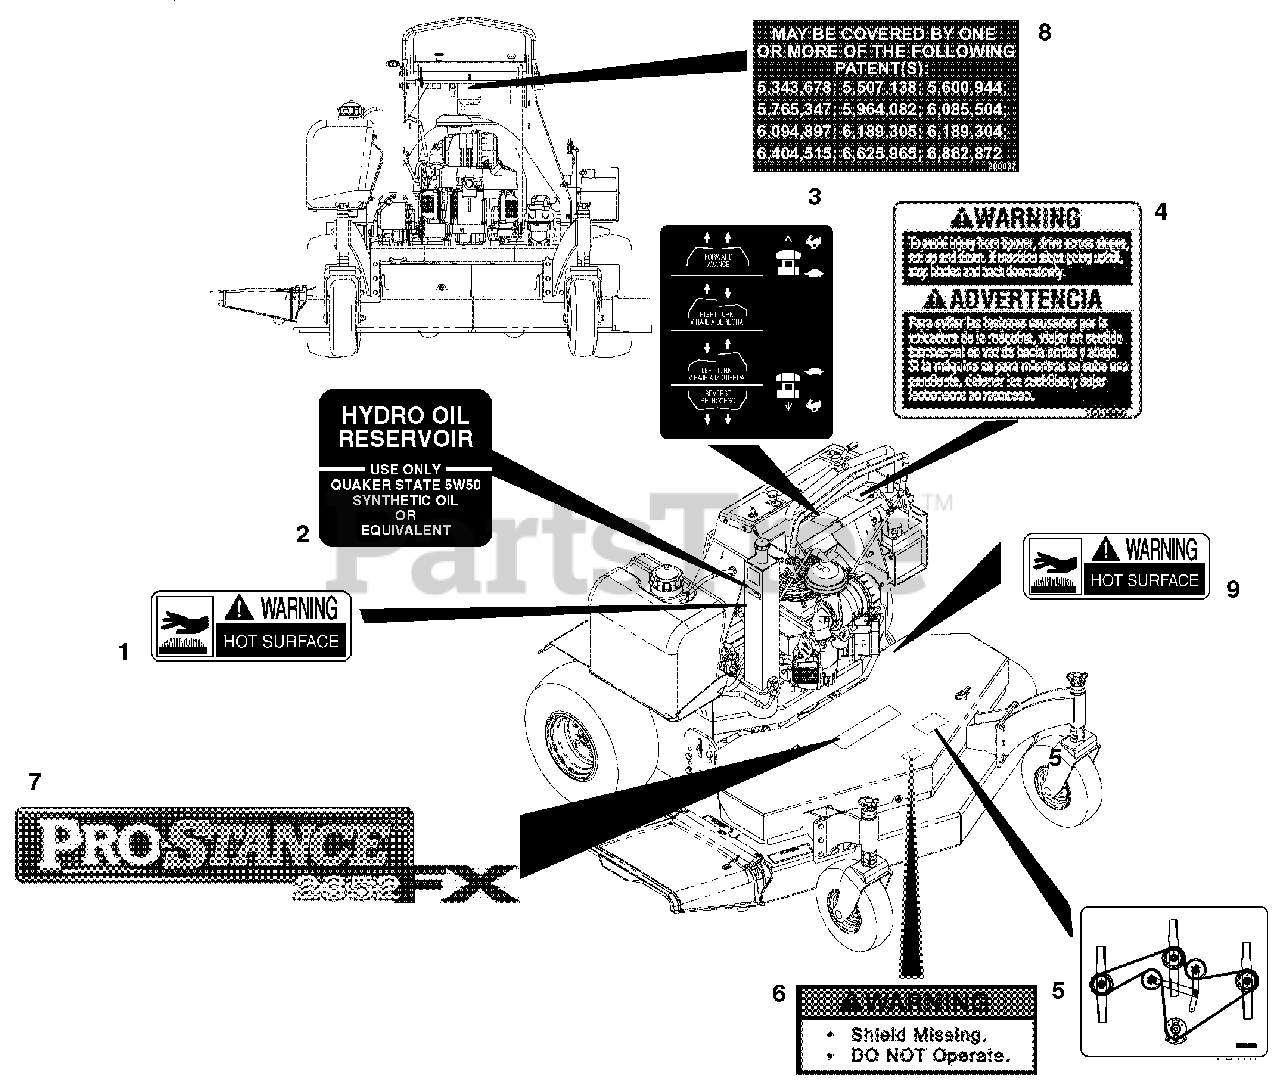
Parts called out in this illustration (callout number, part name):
1	Decal, Warning, Hot Surface
2	Decal, Hydro Oil Reservoir
3	Decal, Directional Control
4	Decal, Warning, Slope
5	Decal, Belt Path
6	Decal, Warning, Shield
7	Decal, Pro-Stance 1952FX (994101)
8	Decal, Patent
9	Decal, Warning, Hot Surface (994102)
